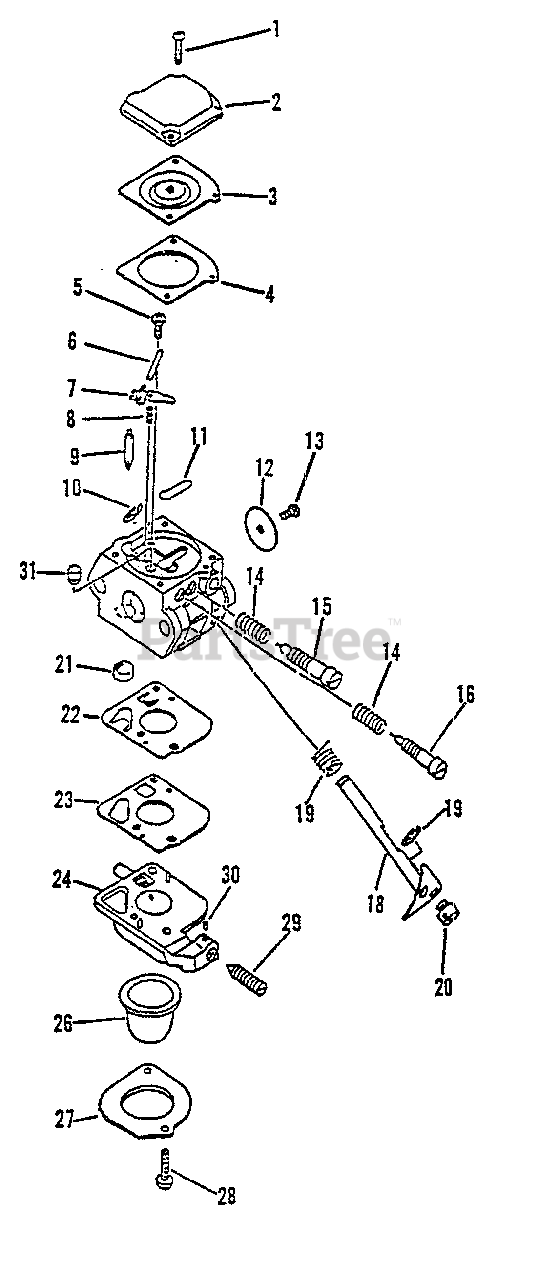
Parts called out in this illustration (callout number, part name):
2	COVER, METERING
3	DIAPHRAGM
4	GASKET, METERING
5	SCREW, METERING LEVER PIN
6	PIN
7	LEVER, METERING
8	SPRING
9	VALVE, NEEDLE
10	RING, RETAINING
11	PLUG, WELCH
12	VALVE, THROTTLE
15	NEEDLE - HIGH SPEED
16	NEEDLE - MIXTURE
17	SPRING, RETURN
18	SHAFT, THROTTLE
19	RING, RETAINING
21	STRAINER
22	DIAPHRAGM, PURGE
23	GASKET, PURGE
24	BASE, PURGE
26	BULB, PURGE
27	RETAINER, PURGE BULB
28	SCREW, RETAINER
29	SCREW, IDLE ADJUST
30	PIECE, FRICTION
31	NOZZLE, CHECK VALVE
